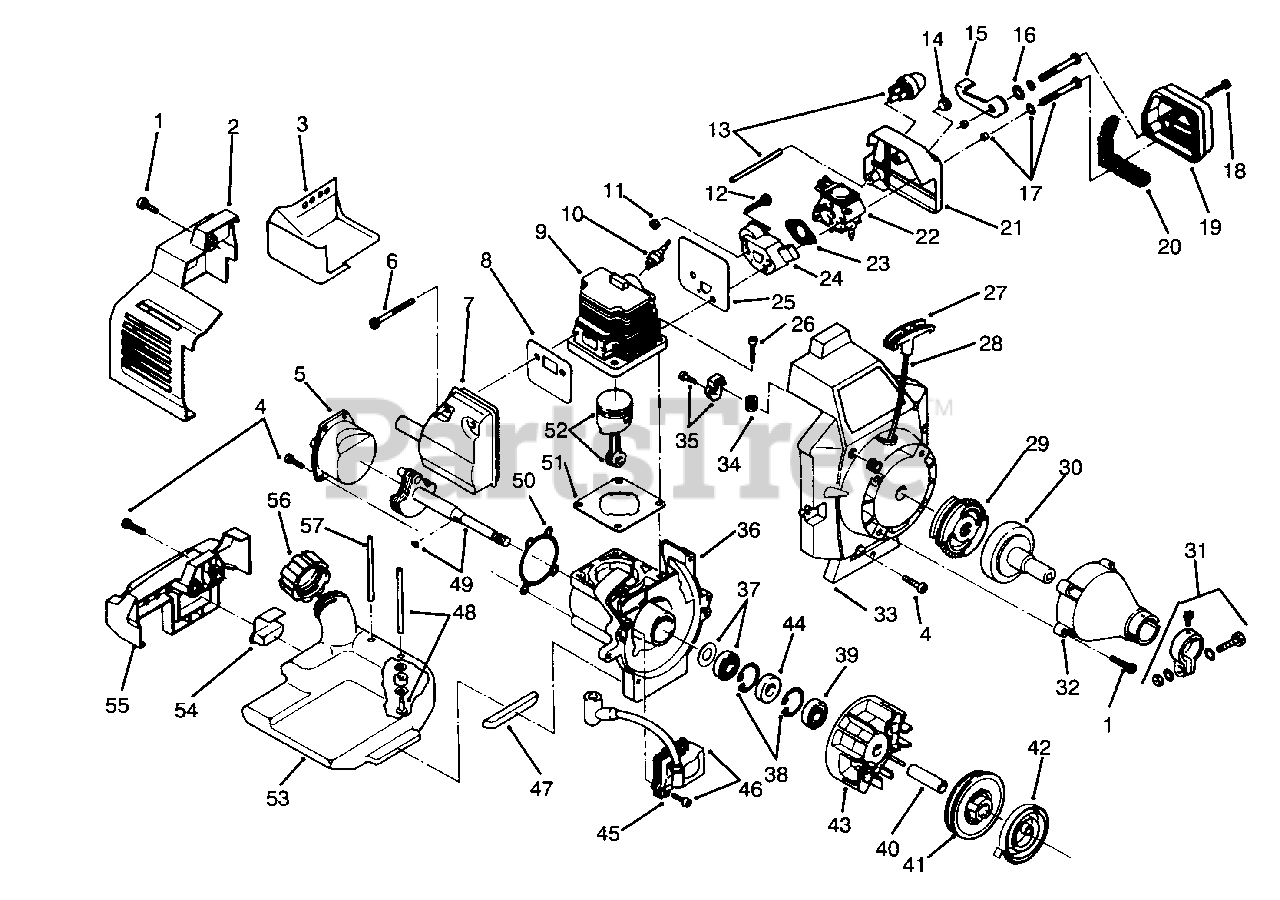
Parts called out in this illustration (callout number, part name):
2	Cover-Rear
3	Shield-Heat
4	Screw-Mounting
5	Cap-Crankcase (Incl. Ref. No. 4)
6	Screws-Muffler Mounting
7	Assembly-Muffler (Incl. Ref. No. 8)
8	Gasket-Muffler
9	Cylinder (Incl. Ref. No. 51)
10	Spark Plug
11	Spacer Nut Set
12	Spacer Screw Set
13	Primer Bulb and Hose
14	Switch-Plug
15	Lever-Choke
16	Washer-Wave
17	Assy.-Screw,Carb. Mount
18	Screw
19	Cover-Air Cleaner
20	Element-Air Filter
21	Assy.-Base,Air Cleaner
22	Assembly-Carburetor (Incl. Ref. No. 23)
23	Gasket-Carb. (10 Pack)
24	Assembly-Spacer,Carb. (Incl. Ref. No. 11 & 12)
25	Gasket-Cylinder/Carb.
27	Handle-Pull
28	Rope-Starter
29	Assembly-Rotor Clutch
30	Assembly-Clutch Drum
31	Assembly-Clamp
32	Assembly-Housing, Clutch (Incl. Ref. No. 1)
33	Assembly-Housing (Incl. Ref. No. 4)
34	Guide-Rope
35	Retainer-Pulley
36	Assembly-Crankcase (Incl. Ref. No. 5, 37-39, 44, 49-50)
37	Assembly-Bearing,Inner
38	Assembly-Snap Ring
39	Bearing-Outer
41	Pulley-Recoil
42	Spring-Recoil
43	Assembly-Flywheel
45	Tab-Ground
46	Assembly-Module
47	Pad-Fuel Tank, Front
48	Assembly-Fuel Line
49	Assembly-Power Shaft
50	Gasket-Cap, Crankcase
51	Gasket-Cylinder
52	Assy.-Piston and Rod
53	Assembly-Fuel Tank
54	Pad-Fuel Tank, Rear
55	Bracket-Fuel Tank
56	Cap-Fuel Tank
57	Fuel Line-Return
